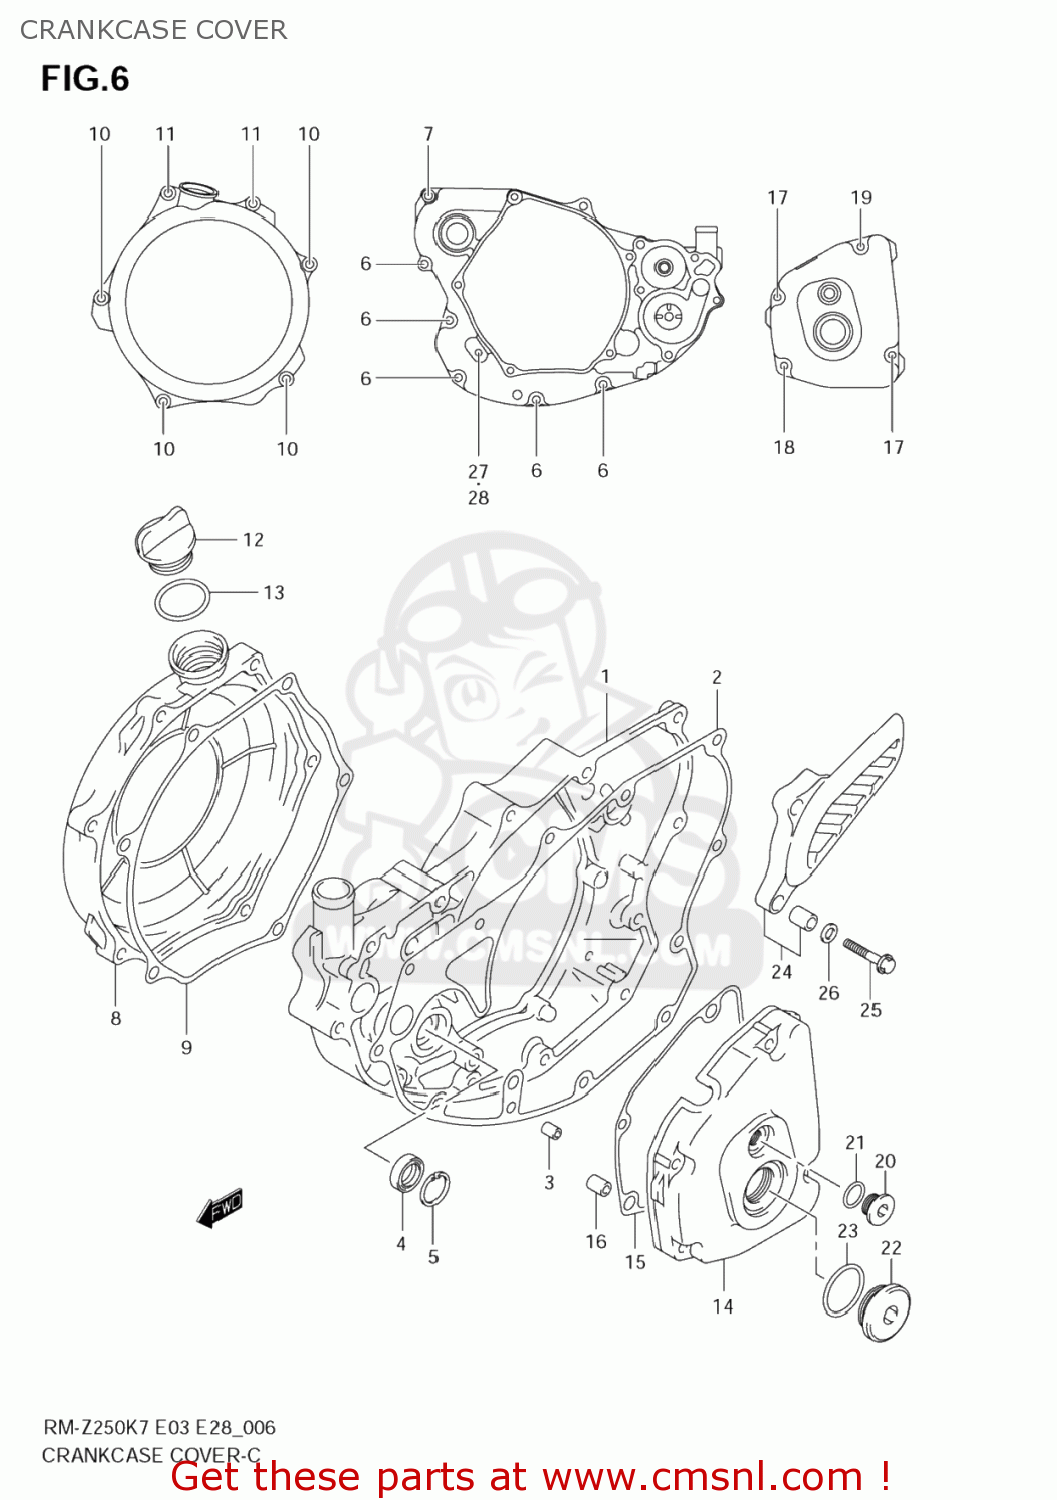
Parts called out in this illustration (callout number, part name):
1	COVER,CLUTCH
2	GASKET,CLUTCH COVER (NAS)
3	PIN
4	SEAL,OIL(12X22X6)
5	CIRCLIP
6	BOLT
7	BOLT
8	COVER,CLUTCH OUTER
9	GASKET,CLUTCH COVER OUTER (NAS)
10	BOLT
11	BOLT
12	PLUG
13	O RING(D:3.1,ID:16.8)
14	COVER,MAGNETO
15	GASKET,MAGNETO COVER (NAS)
16	PIN
17	BOLT
18	BOLT
19	BOLT
20	PLUG(12X9)
21	O RING(D:1.9,ID:9.8)
22	PLUG(26X9)
23	O RING(D:3.1,ID:22.7)
24	COVER,ENGINE SPROCKET
25	BOLT
26	WASHER
27	BOLT
28	GASKET(6.2X11X1).2 (NAS)
